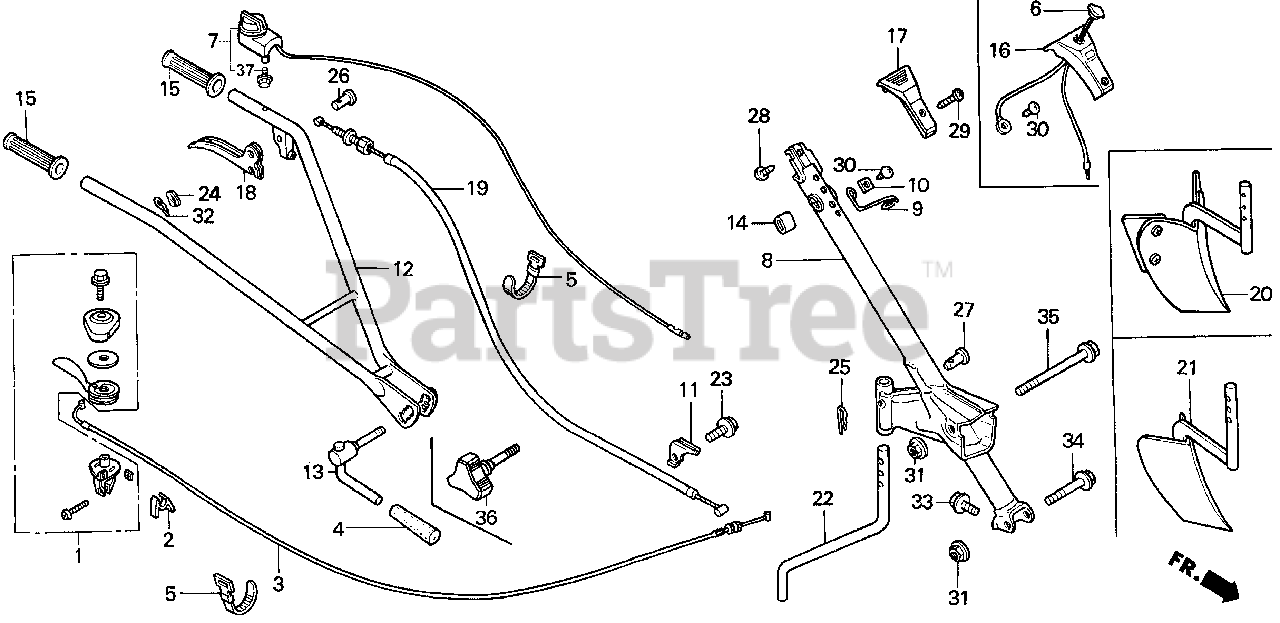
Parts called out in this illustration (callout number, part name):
1	LEVER ASSY., THROTTLE
2	M-CLIP (STEEL PLATE CLIP)
3	CABLE, THROTTLE
4	GRIP, FR. CLUTCH LEVER
5	BAND B1, CABLE Use up to Frame SN 1001879.
7	SWITCH, ENGINE STOP
8	HOLDER, COLUMN *NH35M* (CLOUD SILVER METALLIC)
9	GUIDE, CABLE
10	BRACKET, CABLE GUIDE
11	STOPPER, CABLE
12	PIPE (UPPER)
13	LEVER, HANDLE ADJUSTING
14	STOPPER, ADJUSTING
15	GRIP, L. HANDLE
17	COVER, HANDLE *NH278* (QUARTER GRAY)
18	LEVER, CLUTCH
19	CABLE, MAIN CLUTCH
20	RIDGER ASSY., WIDE
21	RIDGER
23	BOLT, FLANGE (6X12) (CT200)
24	WASHER, WAVE (10MM)
25	PIN, SNAP (7MM)
26	PIN (8X18)
27	PIN (7X48)
28	SCREW, TAPPING (5X16)
29	SCREW, TAPPING (5X25)
30	SCREW, TAPPING (5X10)
31	NUT, FLANGE (8MM)
32	PIN, LOCK (8MM)
33	BOLT, FLANGE (8X16) Use up to Frame SN 1008045.
33	BOLT, FLANGE (8X16) Use from Engine SN 1000016.
34	BOLT, FLANGE (8X55)
35	BOLT, FLANGE (8X80)
37	BOLT (3X12) (SEMS)
